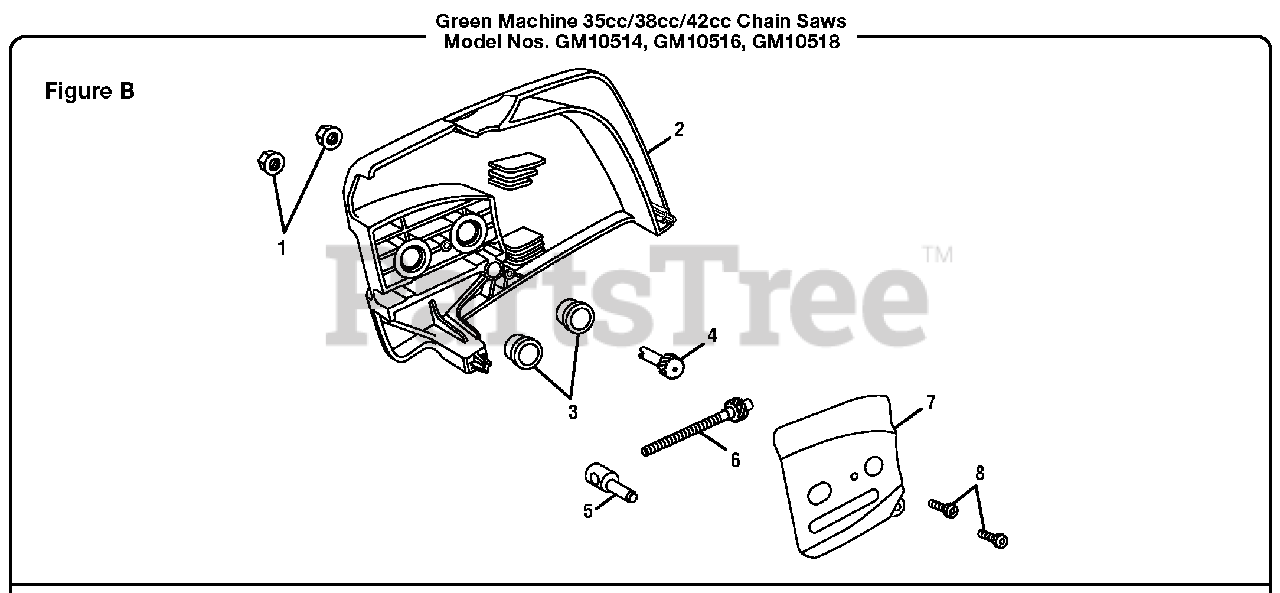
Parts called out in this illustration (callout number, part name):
1	Hex Nut (5/16-18)
2	Clutch Cover
3	Clutch Cover Insert
4	Adjusting Gear
5	Adjusting Nut
6	Adjusting Screw
7	Guide Plate
8	Screw (M4, Torx T20)
